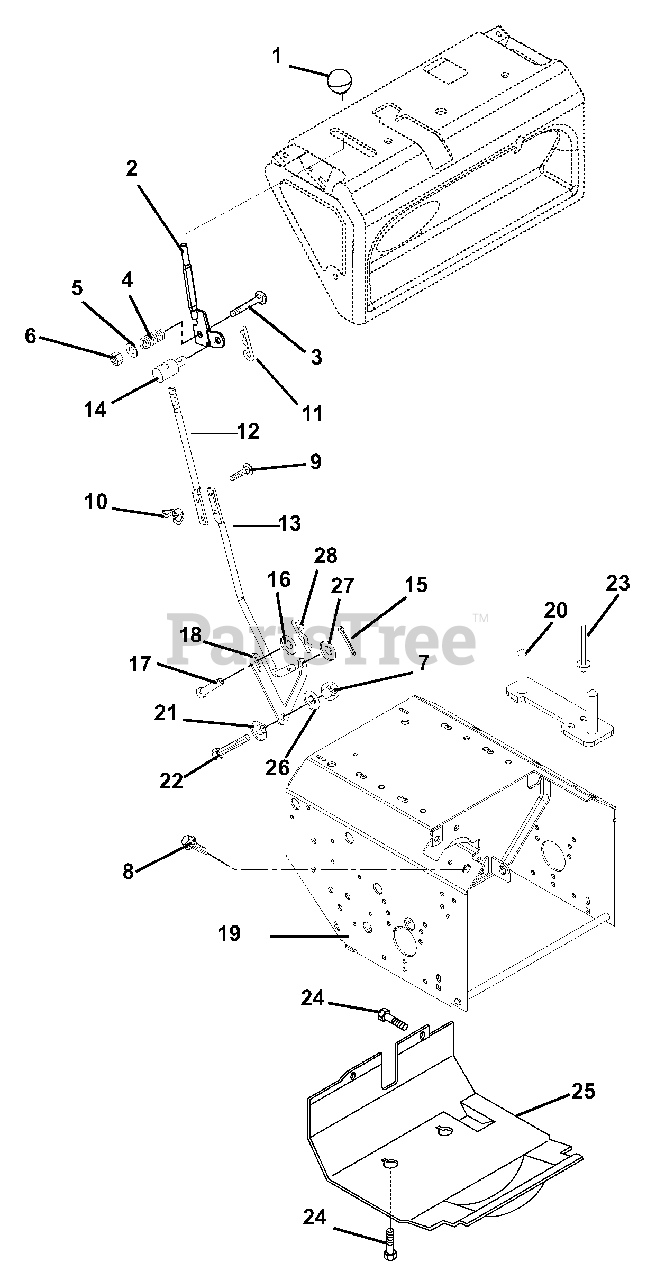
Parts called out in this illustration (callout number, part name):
1	KNOB,BALL -BLACK 1.47" .375-16
2	WMT, SHIFT LEVER
3	@BLT-RDHDSQNK .38-16X2.50 G5YZ
4	SG-COMP .125X.781X1.250
5	@WSHR-FL-STL.438X1.00X.083 YWZ
6	@NUT-LK-CTR .38-16 YWZC
7	@NUT-LK-CTR .31-18 YWZC
8	BLT-SERHFWH .38-16X.75 YWZC
9	@BLT-RDHDSQNK .25-20X1.00 G5YZ
10	NUT-LK WING .250-20 YWZC
11	PIN-HAIR INT .08X.18X1.18 YWZC
12	ROD, SHIFT-UPPER
13	ROD, SHIFT-LOWER
14	PIVOT, ROD (TRUNNION ) .50
15	@PIN-CTR .12X.75 EXTPRSQCT YWZ
16	WSHR-FL-STL .382X.812X.023YWZC
17	CLEVIS PIN
18	ARM, SHIFT
19	FRAME, MAIN-WELDMENT
20	STRAP, ENGINE BOLT-WELDMENT
21	BSHG-FLG .325X.500X.327X.875
22	@BLT-HEX .31-18X1.00 GR5 YWZC
23	RVT-POP .187X.45 DOME SS FBF64
24	SCR-TAP .31-18X.375 HWH TR YZ
25	COVER, BOTTOM
26	WSHR-FL-STL .328X.875X.062YWZC
27	@WSHR-FL-STL.531X1.06X.095YWZC
28	PIN-HAIR, ENDRIES #25 YWZC
